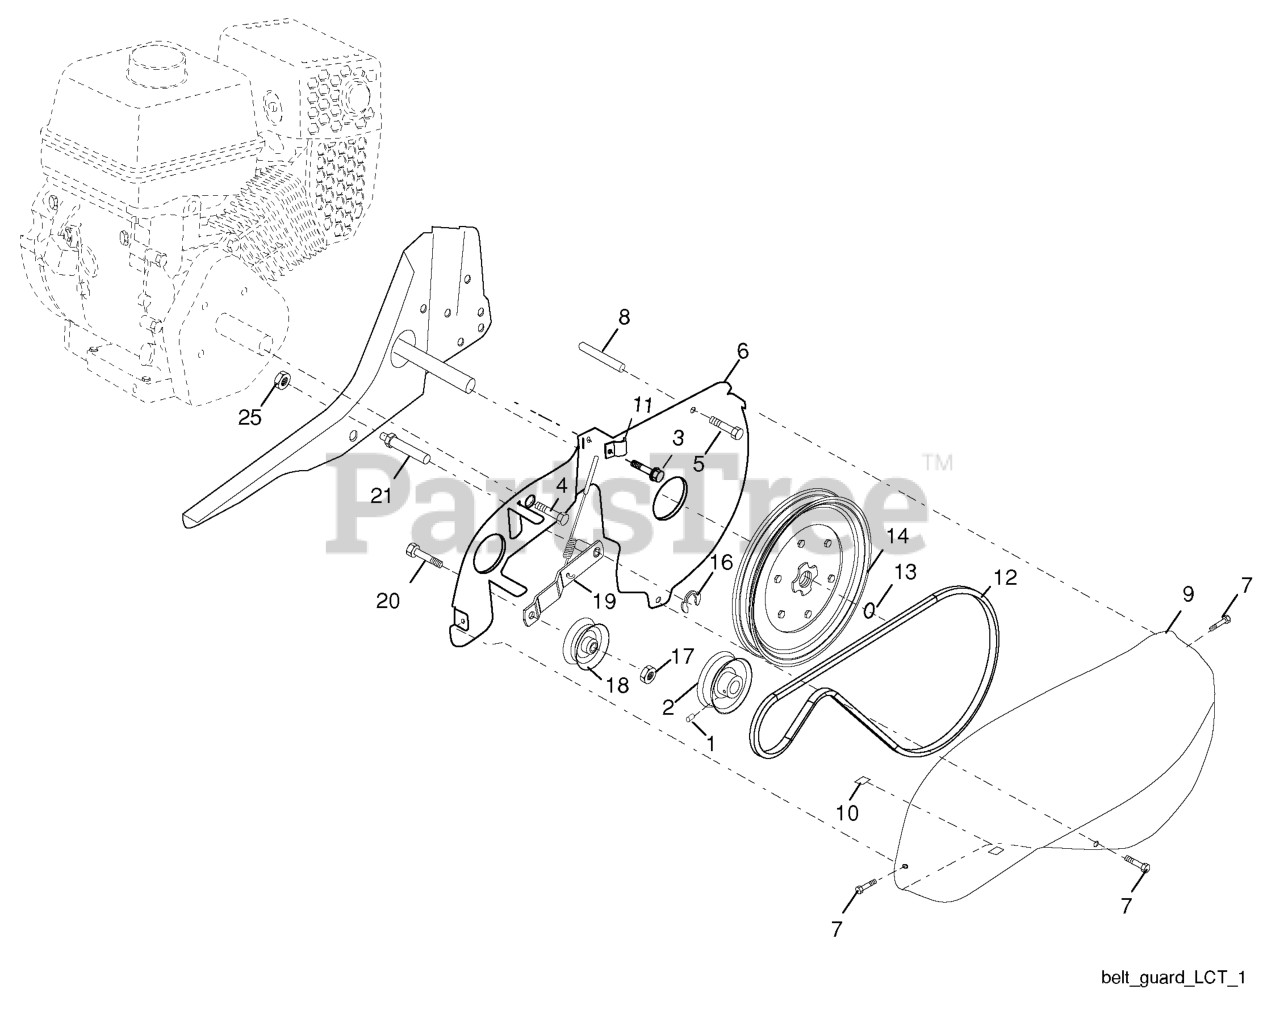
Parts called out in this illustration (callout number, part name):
1	Screw Set 5/16-18 x 3/8 Patch
2	Sheave, Engine
3	Screw, Tap Hex Head
4	Bolt, Hex Head 5/16-24 unf x 1/2
5	Bolt, Thd Roller 1/4-20 x 2-1/2
6	Shield, Inner Belt Guard
7	Screw Hex Wsh Hd #8-18 x 1/2
8	Spacer Split
9	Guard, Belt
10	Pad, Idler
11	Clip, Cable
12	V-Belt
13	Ring, Retainer
14	Sheave, Transmisison
16	Ring, Klip
17	Nut, Hex, Jam 3/8-16
18	Pulley, Idler
20	Bolt, Hex Head 3/8-16 x 1-1/4
21	Shaft, Idler Arm
25	Nut, Hex, Jam 5/16-18
